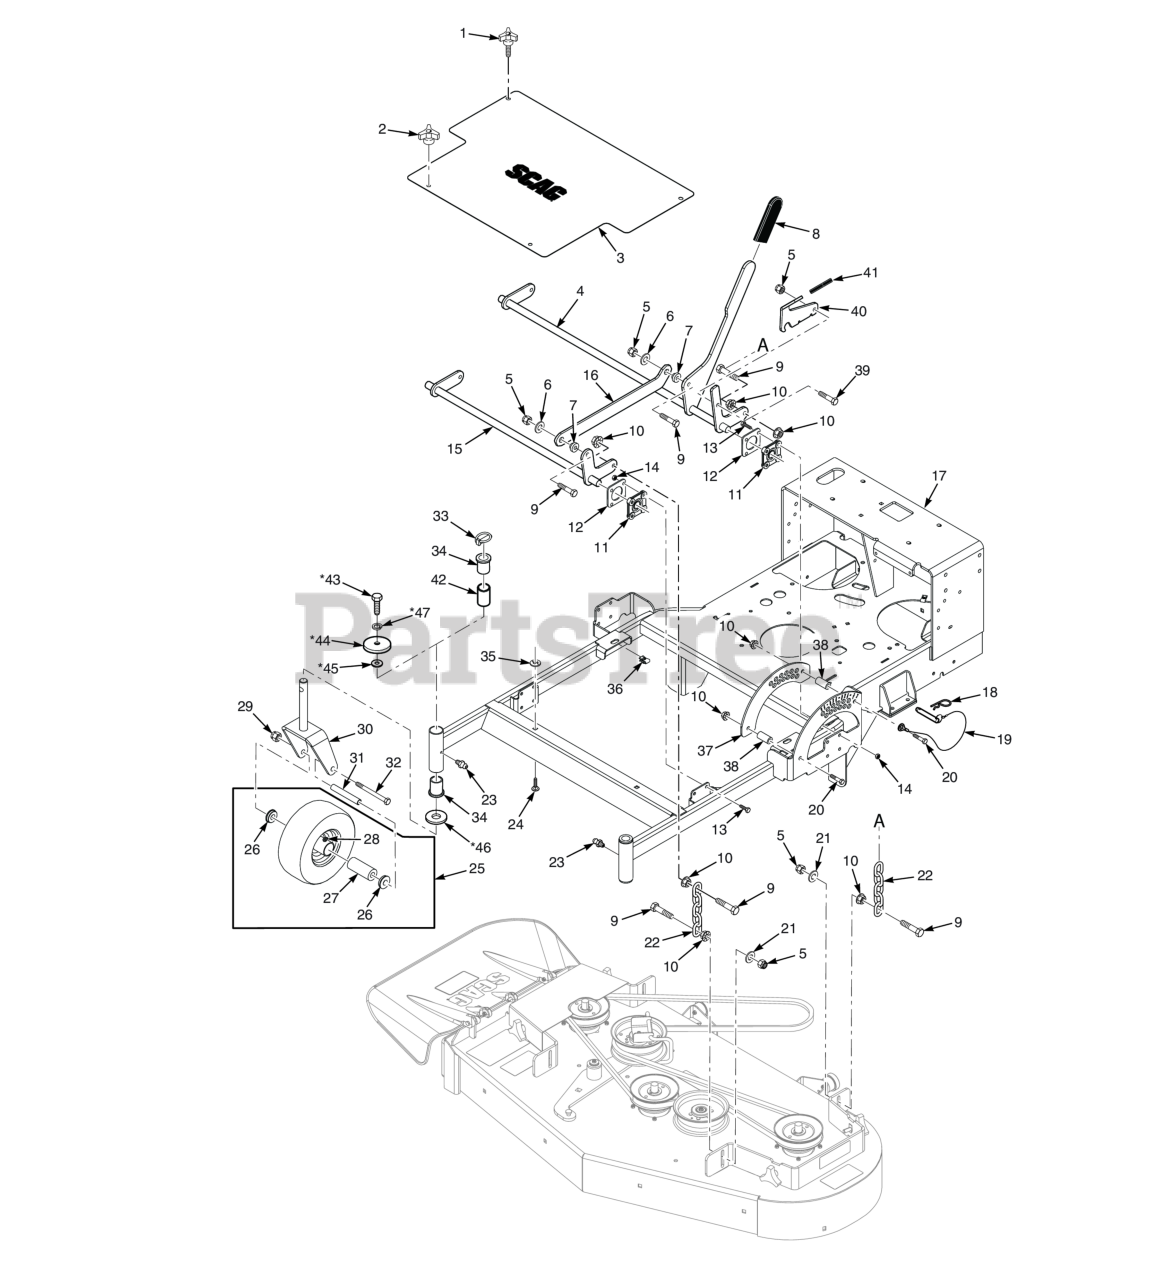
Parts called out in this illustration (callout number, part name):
1	Knob, w/stud 3/8-16 x 1-1/4"
2	Wing Nut, 3/8-16 (Small) Top side
3	Belt Cover w/Decals - SWZT61
4	Deck Bellcrank Assy. - SWZT61
5	HEX NUT, ELASTIC STOP LOCK, 3/8-16
6	Flatwasher, 3/8" Special (.391 x .938 x .105)
7	BUSHING, SPEED ADJUSTMENT LEVER
8	Grip, Deck Lift
9	Bolt, Hex Head, 3/8-16 x 1-1/2"
10	NUT, 3/8-16 SERRATED FLANGE HEX HEAD
11	Bearing, Deck Lift - 48V & 52V
12	Reinforcement, Bearing - 48V & 52V
13	Cpscrw, 5/16-18 x 1"Serrated Flange Hex Head
14	Nut, Center Lock, 5/16-18(32)
15	Deck Lift Weldment, Front - SWZT61
16	Link, Decklift -SWZT61
17	Frame w/Decals (SWZT 61)
18	Hair Pin Cotter, .177" x 3-1/4"
19	Lanyard, Deck Height Pin Assembly
20	Capscrew, Hex Head 3/8-16 x 2-1/2"
21	Flatwasher, 3/8" Special (.391 x .938 x .105)
22	Chain, Deck Lift
23	GREASE FITTING, STR. 1/4-28 SELF TAP.
24	Carriage Bolt, 3/8-16 x 1.0"
25	Caster Wheel Assembly, 11 x 4.0-5
26	Retainer, Bearing, Caster Wheel
27	Roller Bearing, .625 x 3-1/4"
28	GREASE FITTING, 45 DEGREE 1/4-28
29	HEX LOCKNUT, ELASTIC STOP, 1/2-13
30	Caster Yoke - SWZT61
31	Sleeve, Caster Wheel Bearing - SWZT61
32	Bolt, Hex Head 1/2-13 x 5-1/2" (Three Weights Installed)
33	Quick Pin, .438" Dia.
34	Bronze Bushing, 7/8 ID x 1.0 Flanged
35	Nut, Push-On - 3/8" Dia.
36	U-Nut, 3/8-16 (short)
37	Bracket, Deck Height
38	Spacer
39	Bolt, Hex Head, 3/8-16 x 1 Gr. 5
40	Lever Assembly, Deck Latch
41	Grip, Deck Transport Lock
42	Spacer, Caster Bearing
43	Bolt, Hex Head, 3/8-16 x 1 Gr. 5
44	Flatwasher, 3/8-.406 x 2.25" x .1875
45	Flatwasher, 7/16" (.500 x 1.25 x .083")
46	Spacer, Yoke
47	Lockwasher, 3/8" Spring, Kawasaki FX / FS
